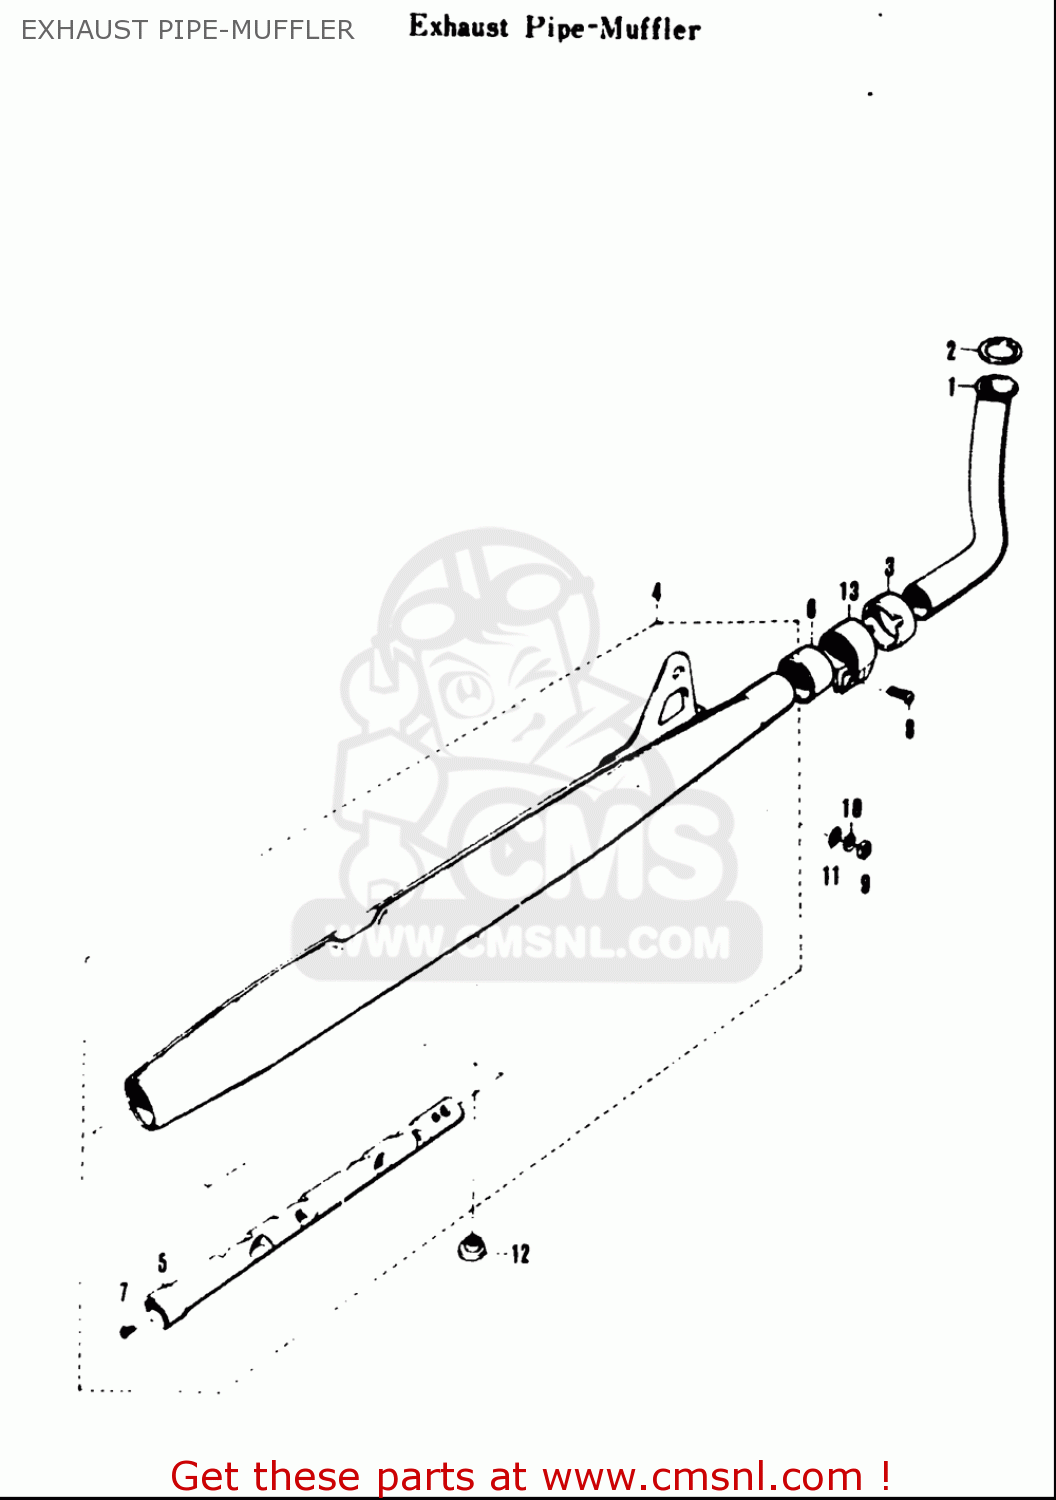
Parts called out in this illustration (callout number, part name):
1	PIPE,EXHAUST
2	GASKET,EXHAUST PIPE (NAS)
3	CLAMP,EXHAUST PIPE
5	PIPE,BAFFLE
6	CONNECTOR,MUFFLER
7	SCREW(5X6)
9	NUT
10	WASHER,LOCK
11	WASHER,LOCK
12	CUSHION(11.5X22X20)
